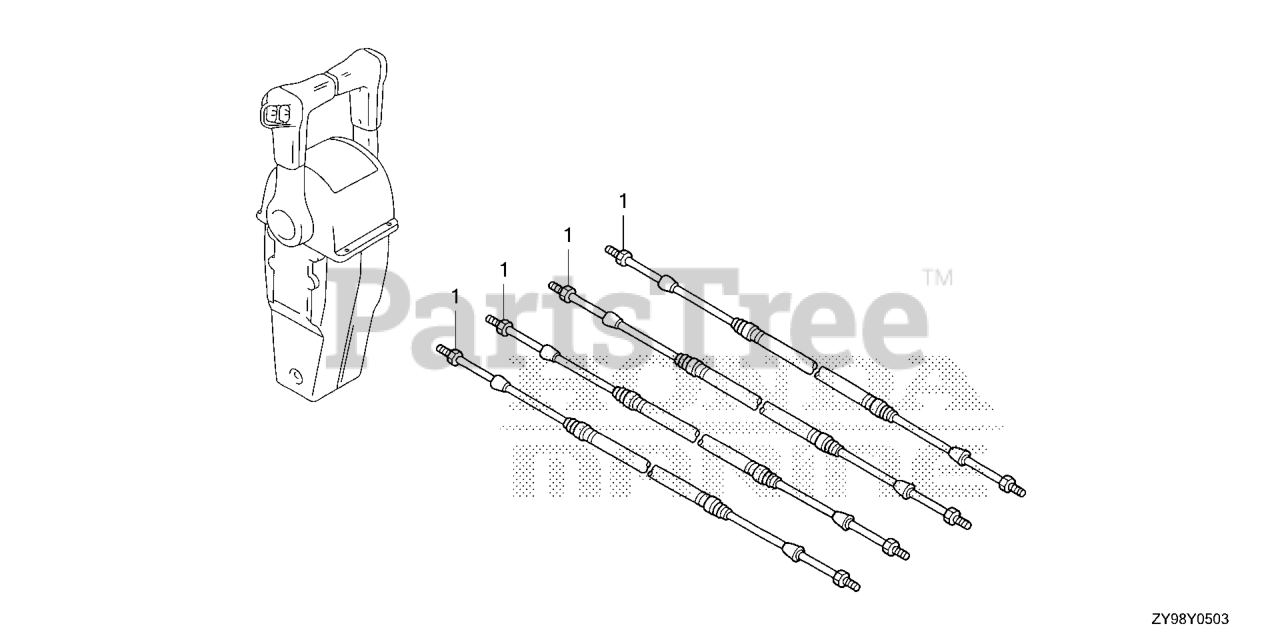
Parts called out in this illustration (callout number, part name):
1	CABLE ASSY., PUSH-PULL (33HPC-5FT)
1	CABLE ASSY., PUSH-PULL (33HPC-6FT)
1	CABLE ASSY., PUSH-PULL (33HPC-7FT)
1	CABLE ASSY., PUSH-PULL (33HPC-8FT)
1	CABLE ASSY., PUSH-PULL (33HPC-9FT)
1	CABLE ASSY., PUSH-PULL (33HPC-10FT)
1	CABLE ASSY., PUSH-PULL (33HPC-11FT)
1	CABLE ASSY., PUSH-PULL (33HPC-12FT)
1	CABLE ASSY., PUSH-PULL (33HPC-13FT)
1	CABLE ASSY., PUSH-PULL (33HPC-14FT)
1	CABLE ASSY., PUSH-PULL (33HPC-15FT)
1	CABLE ASSY., PUSH-PULL (33HPC-16FT)
1	CABLE ASSY., PUSH-PULL (33HPC-17FT)
1	CABLE ASSY., PUSH-PULL (33HPC-18FT)
1	CABLE ASSY., PUSH-PULL (33HPC-19FT)
1	CABLE ASSY., PUSH-PULL (33HPC-20FT)
1	CABLE ASSY., PUSH-PULL (33HPC-21FT)
1	CABLE ASSY., PUSH-PULL (33HPC-22FT)
1	CABLE ASSY., PUSH-PULL (33HPC-23FT)
1	CABLE ASSY., PUSH-PULL (33HPC-24FT)
1	CABLE ASSY., PUSH-PULL (33HPC-25FT)
1	CABLE ASSY., PUSH-PULL (33HPC-26FT)
1	CABLE ASSY., PUSH-PULL (33HPC-27FT)
1	CABLE ASSY., PUSH-PULL (33HPC-28FT)
1	CABLE ASSY., PUSH-PULL (33HPC-29FT)
1	CABLE ASSY., PUSH-PULL (33HPC-30FT)
1	CABLE ASSY., PUSH-PULL (33HPC-31FT)
1	CABLE ASSY., PUSH-PULL (33HPC-32FT)
1	CABLE ASSY., PUSH-PULL (33HPC-33FT)
1	CABLE ASSY., PUSH-PULL (33HPC-34FT)
1	CABLE ASSY., PUSH-PULL (33HPC-35FT)
1	CABLE ASSY., PUSH-PULL (33HPC-36FT)
1	CABLE ASSY., PUSH-PULL (33HPC-37FT)
1	CABLE ASSY., PUSH-PULL (33HPC-38FT)
1	CABLE ASSY., PUSH-PULL (33HPC-39FT)
1	CABLE ASSY., PUSH-PULL (33HPC-40FT)
